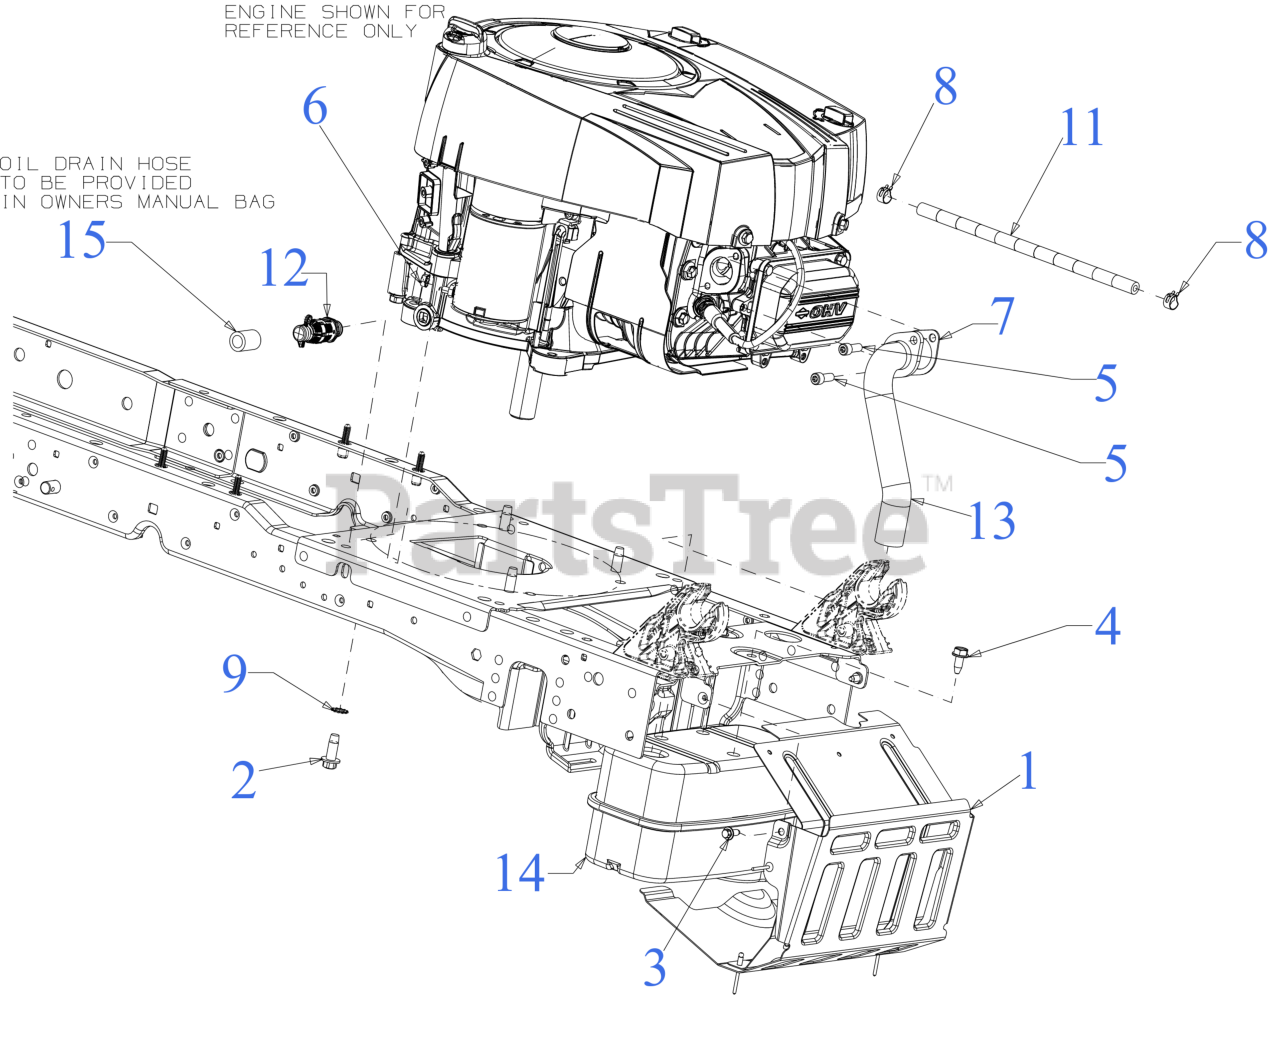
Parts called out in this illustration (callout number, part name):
1	MUFFLER SHIELD ASSEMBLY
2	SCREW 3/8-16 x 1
3	SCREW M6-1 x .625
4	SCREW M8-1.25 x .750
5	SCREW 5/16-18 x .625
6	SEMS NUT 1/4-20
7	EXHAUST GASKET
8	HOSE CLAMP 1/20
9	LOCK WASHER 3/8
11	FUEL HOSE LOW PERMEATION 16"
12	OIL DRAIN VALVE
13	EXHAUST PIPE (B&S) (SINGLE)
14	EXHAUST MUFFLER (SINGLE)
15	DRAIN HOSE 14''
